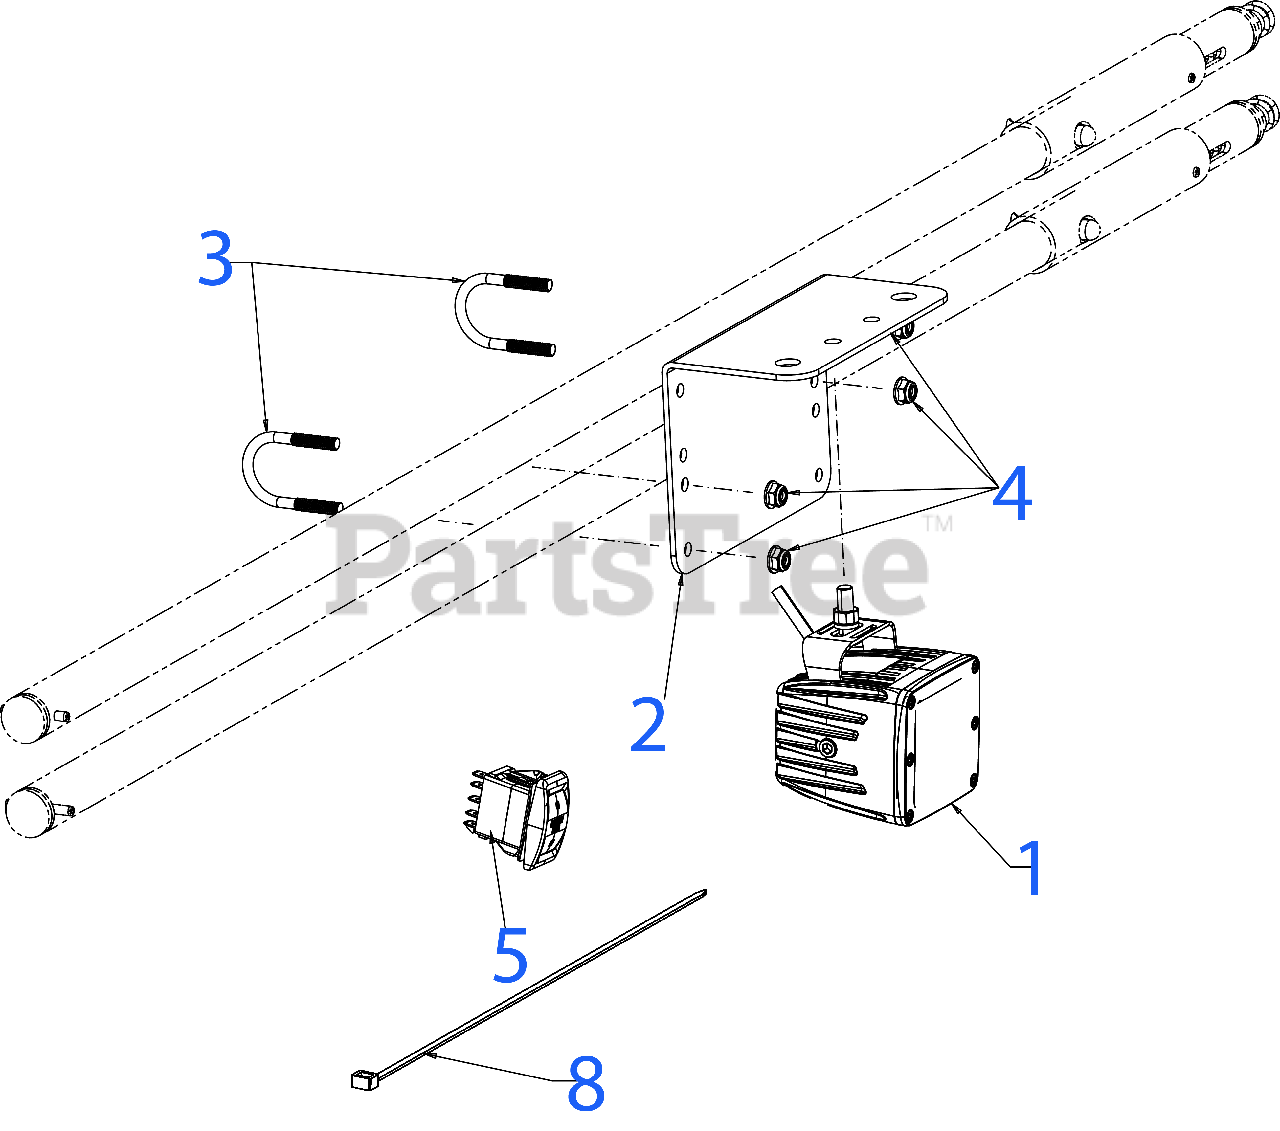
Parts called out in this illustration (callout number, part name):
1	LED CUBE FLOOD LIGHT
2	FLAG/LIGHT MOUNT
3	U-BOLT 1/4-20 HEXFLGLK
4	FLANGE LOCK NUT
5	ROCKER SWITCH FOR LIGHT BAR
8	TIE:CBL:14.5" LONG
